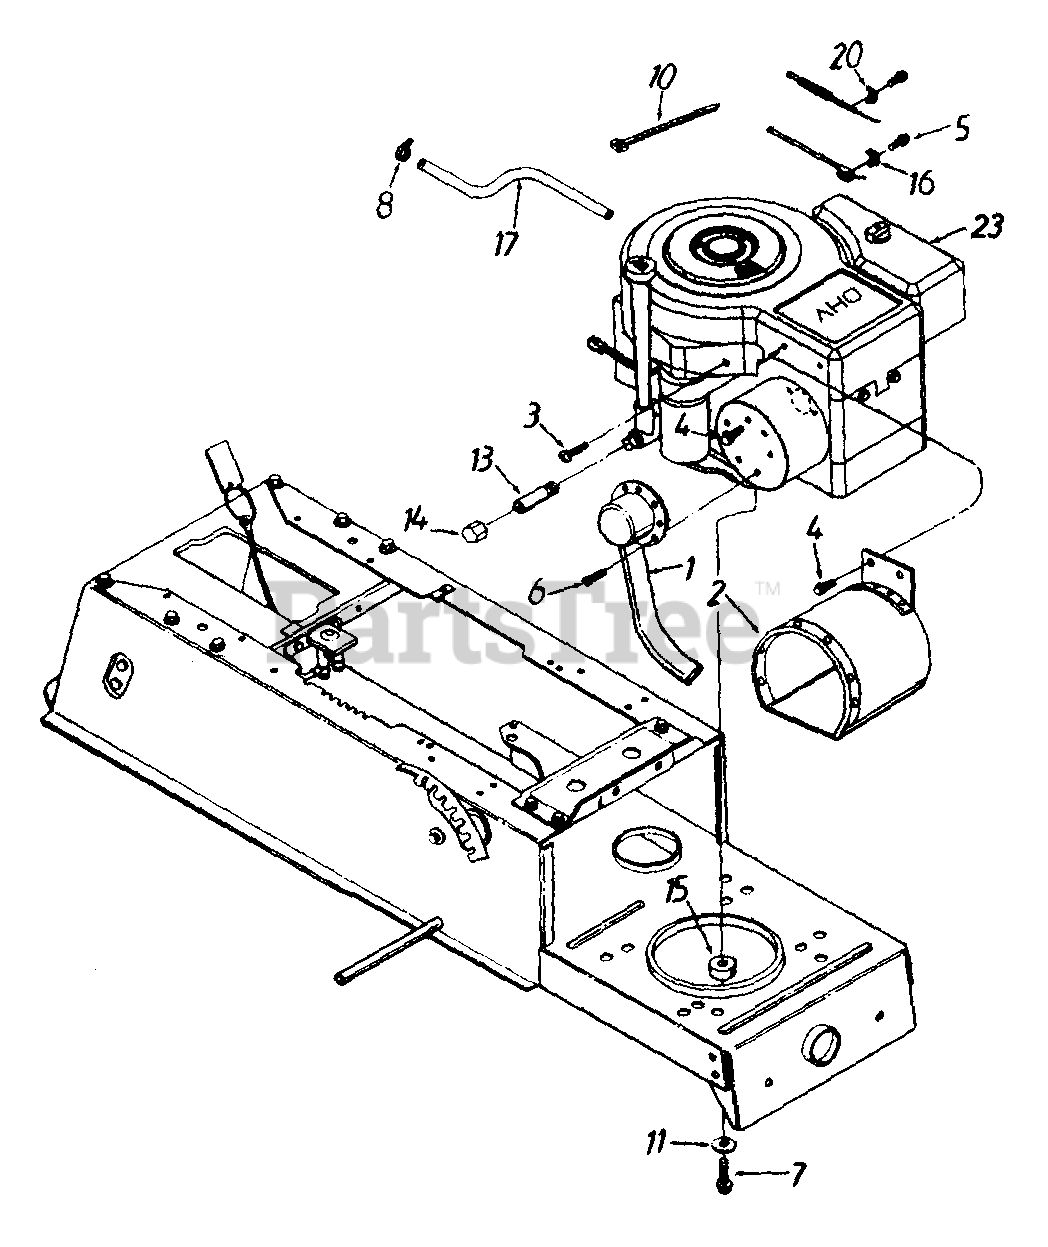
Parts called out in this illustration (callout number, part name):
1	Exhaust Pipe Ass'y.
2	Heat Shield Ass'y.
3	Pan Hd. Mach. Scr. 5/16-18 x .75"
4	Hex Wash. Hd. Scr. 1/4-20 x .5"
5	Hex Slot Wash. Hd. #10-32 x 5/8" Lg.
6	Hex Wash. Hd. F-Tap Scr. #8-32 x .38"
7	Hex L-Wash. TT-Tap Ser. 3/8-16 x 1.5"
8	Hose Clamp - .49" Dia.
10	Cable Tie - 4" I.D.
11	Flat Wash. 3/8" I.D. x 1.25" O.D.
13	Pipe Nipple 3/8-18 NPT x 2" Lg.
14	Cap - Oil Drain
15	Shld. Spacer .38" I.D. x 1.25" O.D.
16	Casing Clamp
17	Fuel Line Hose
20	Casing Clamp
23	Engine
